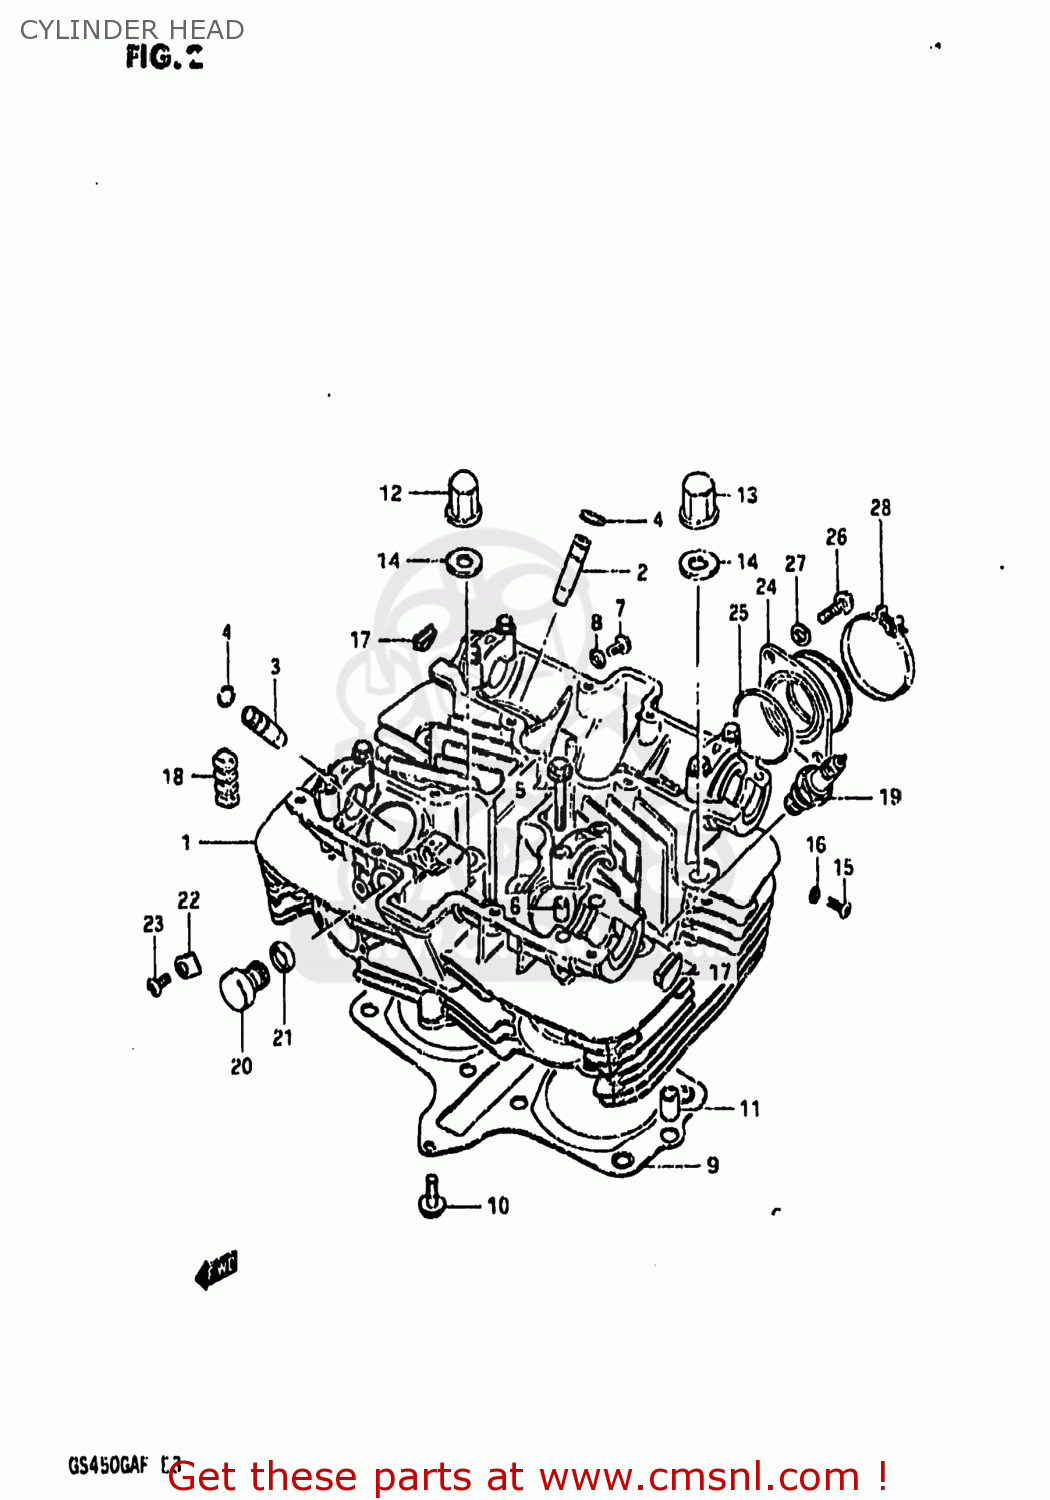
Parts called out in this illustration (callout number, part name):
1	HEAD SET,CYLINDER
2	GUIDE,INTAKE VALVE
3	GUIDE,EXHAUST VALVE
4	RING,SNAP
5	BOLT(6X39)
6	PIN(6.2X8X11)
7	BOLT
8	WASHER
9	GASKET,CYLINDER HEAD (MCA)
10	BOLT 6X30
11	PIN
12	NUT
13	NUT
14	GASKET(10.5X22X2) (NAS)
15	SCREW
16	GASKET(5.3X9.3X1.2) (NAS)
17	PLUG
18	PAD,CYLINDER
19	PLUG,SPARK
20	PLUG,TACH GEAR SLEEVE HOLE
21	SEAL,TACHOMETER DRIVEN
22	PLATE,TACH DRIVE GEAR SLEEVE
23	SCREW(5X12)
24	PIPE,INTAKE
25	O-RING (D:2.4 ID:39.7)
26	SCREW
27	LOCK WASHER
28	CLAMP
